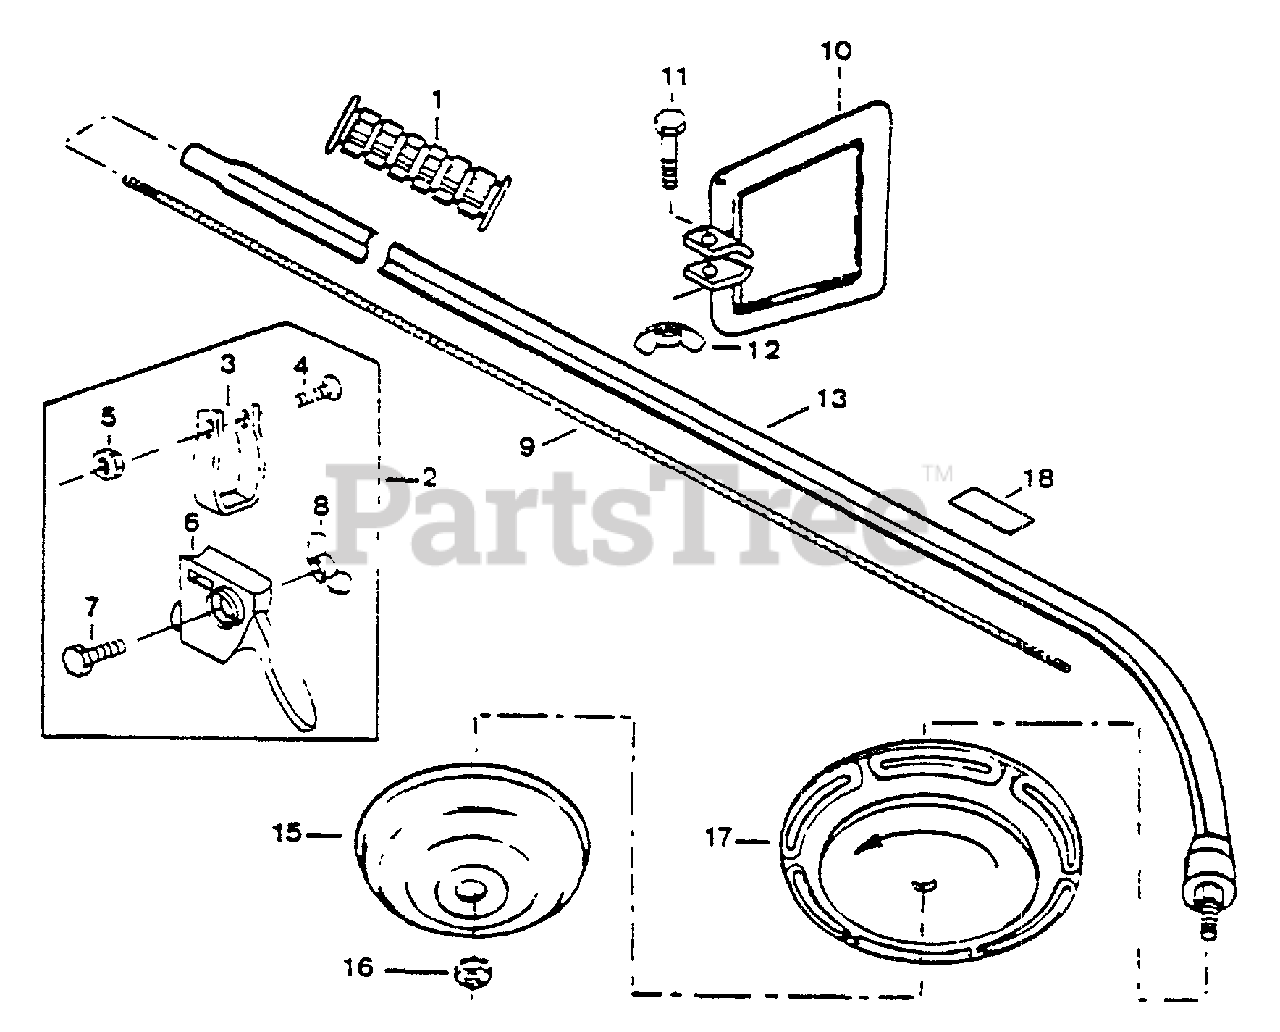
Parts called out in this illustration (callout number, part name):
2	CONTROL CABLE ASSY
3	CLAMP, THROTTLE
4	SCREW - 10-32
5	NUT - 10-32
6	Lever Throttle w/Body
7	SCREW - 10-32 X 1"
8	WINGNUT - 50-32
9	DRIVESHAFT - FLEXIBLE
10	Guide Handle
11	SCREW - 1/4-20
12	WINGNUT - 1/4-20
13	DRIVESHAFT ASSY - LEFT
14	Mono-Head w/.080 line complete
15	LID
16	SCREW - 1/4-20
17	Head Body Mono-Head
18	LABEL - LUBRICATION
